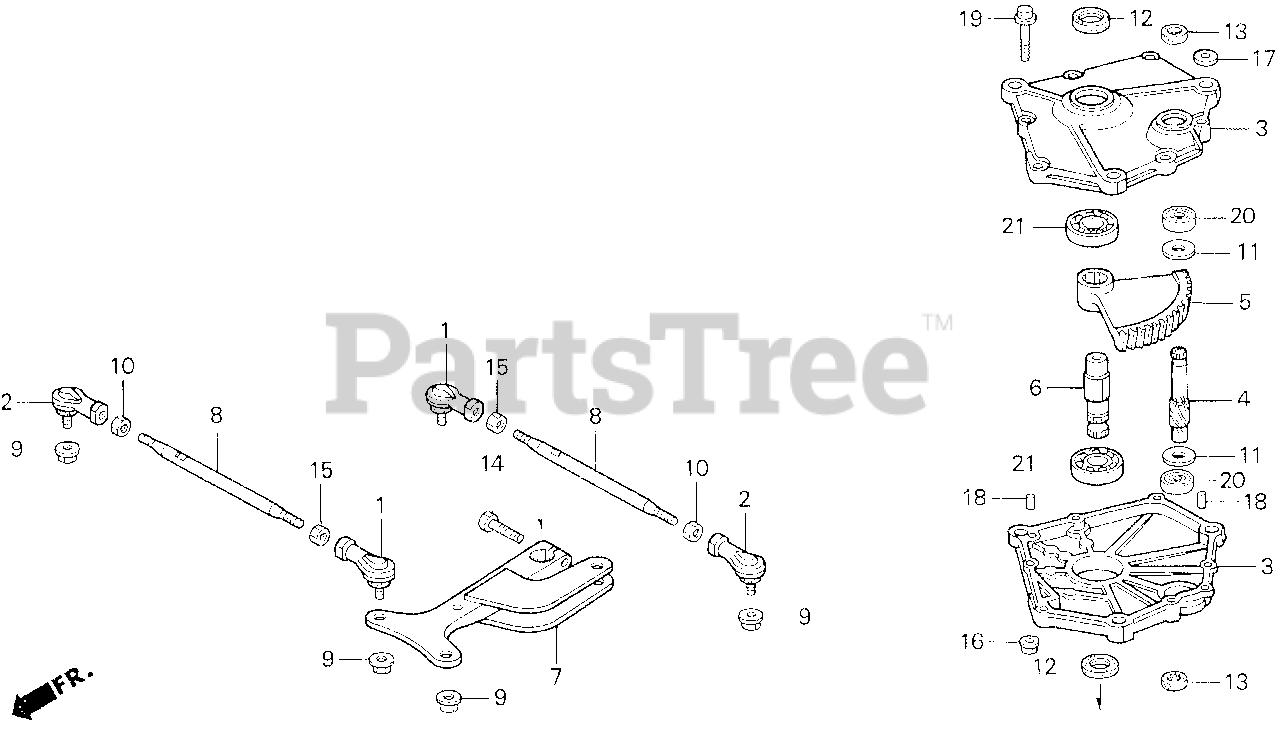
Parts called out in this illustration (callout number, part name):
1	JOINT, R. BALL (ER10)
2	JOINT, L. BALL (ER10)
3	CASE, STEERING GEAR
4	PINION, STEERING
5	GEAR, STEERING
6	SHAFT, STEERING SECTOR
7	ARM, PITMAN
8	TIE ROD, FR.
9	NUT, SELF-LOCK (10MM)
10	NUT, L. HEX. (10MM)
11	WASHER, THRUST (15X1)
12	DUST SEAL (37X25X6)
13	DUST SEAL, CONNECTING ROD PIVOT
14	BOLT, HEX. (10X40)
15	NUT, HEX. (10MM)
16	NUT, FLANGE (6MM)
17	WASHER, PLAIN (10MM)
18	PIN, DOWEL (5X8)
19	BOLT, FLANGE (6X40)
20	BEARING, RADIAL BALL (6202)
21	BEARING, RADIAL BALL (6205)
